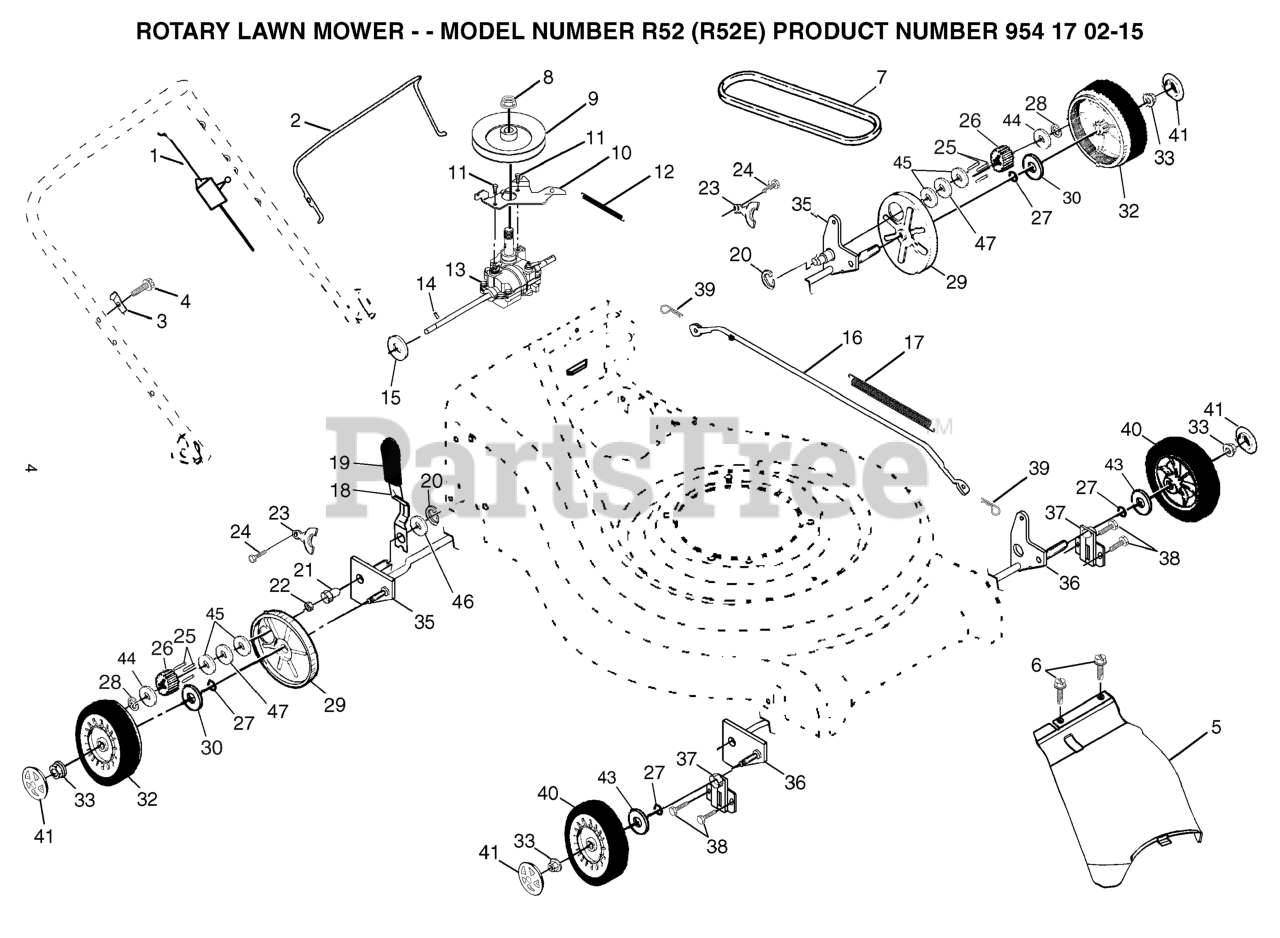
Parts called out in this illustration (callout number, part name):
1	DRIVE CABLE
3	DOWNSTOP BRACKET
5	COVER DRIVE
8	FLANGED LOCKNUT 3/8-16 ZINC
10	BELT GUIDE
11	Screw, Hex Washer Head #10-24 x .668
13	TRANSMISSION ASM. (WALK)
14	PIN.SPRING.THRUST
15	THRUST WASHER
16	ROD CONNECTING
17	SPRING
18	SPRING
19	KNOB.EXT.ERGO.BLACK
21	RP BEARING SUPPORT
22	BEARING, BALL
23	BRACKET
25	PAWL.DRIVE.ETCHED
26	PINION.DRIVE.WALK
27	O-RING
28	E-RING 7/16 RE
29	DUST COVER, WHEEL
30	WASHER FLUT
32	WHEEL.9X2.PR.LP.RADIAL.BK.BB.3
33	HEX FLANGE LOCKNT
35	SHAFT ASSY
36	SHAFT ASSY
37	RETAINER.FRONT.SHAFT
39	RETAINER CLIP
40	WHEEL ASMBLY FRONT
41	CAP.HUB.ARC.SPOKE.8".LP
42	WASHER.ZINC.PLATED
43	WASHER.FLAT.1/2
45	WASHER.BELLEVILLE (3 2 LB)
